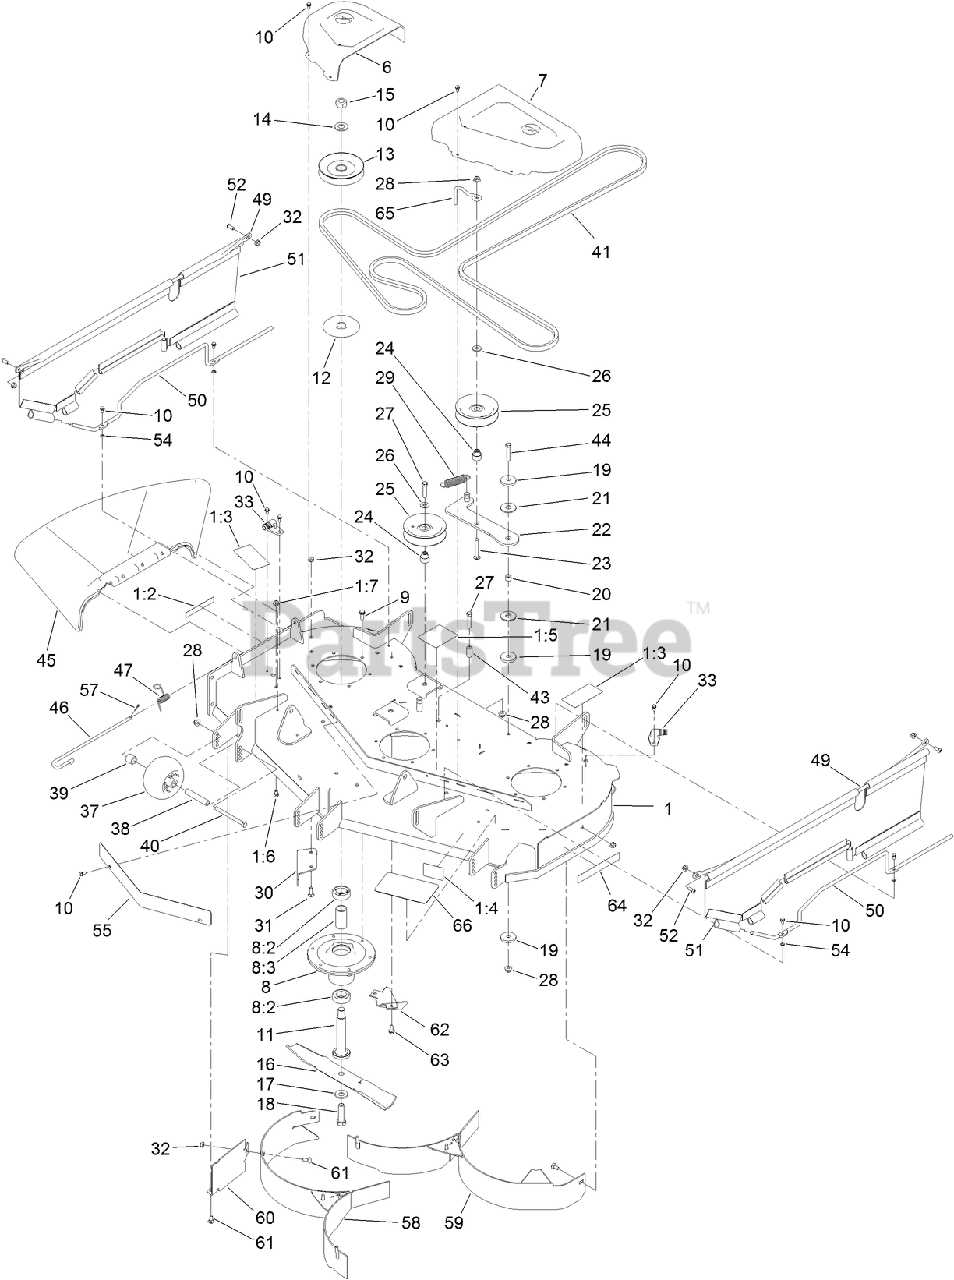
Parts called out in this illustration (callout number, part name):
1	DECK ASM
1:2	DECAL-DANGER
1:3	DECAL-DANGER, DECK
1:4	DECAL-SCALP, ANTI
1:5	DECAL-ROUTING, BELT
1:6	SCREW-HH
1:7	NUT-HF, NI
6	COVER-BELT, RH
7	COVER-BELT, LH
8	SPINDLE ASM
8:2	BEARING-BALL
8:3	SPACER-BEARING
9	SCREW-TAPTITE
10	SCREW-HWH
11	SHAFT-SPINDLE
12	SHIELD-BEARING
13	PULLEY
14	WASHER
15	NUT-HEX
16	BLADE-MULCH, 16.50 INCH
17	WASHER-BELLEVILLE
18	SCREW-BLADE
19	WASHER-PLAIN
20	BUSHING-LEVER, LIFT
21	WASHER-FRICTION, COMPOSITE
22	ARM-IDLER
23	SCREW-CARR
24	BUSHING-IDLER
25	PULLEY-IDLER, FLAT
26	WASHER-HARDENED
27	SCREW-HH
28	NUT-HF, NI
29	SPRING-EXTENSION
30	BAFFLE-CUTOFF
31	SCREW-CARR
32	NUT-HF, NI
33	FITTING-WASHOUT
37	ROLLER-SCALP, ANTI
38	TUBE-SPANNER
39	SPACER-AXLE, REAR
40	SCREW-HH
41	V-BELT
43	SPACER
44	SCREW-HH
45	DEFLECTOR-DISCHARGE
46	PIN-CHUTE
47	SPRING-TORSION
49	ROD SUPPORT, UPPER
50	ROD SUPPORT, LOWER
51	SIDE GUARD ASM
52	SCREW-HSBH
54	NUT-RETAINING
55	SHIELD-FRONT
57	PIN-COTTER
58	BAFFLE-RECYCLER
59	BAFFLE-RECYCLER
60	GUARD-BAFFLE
61	BOLT-CARR
62	KICKER-FLANGED
63	SCREW-HWHTF
64	DECAL-RECYCLER
65	GUIDE-BELT, IDLER
66	TREAD-STEP
